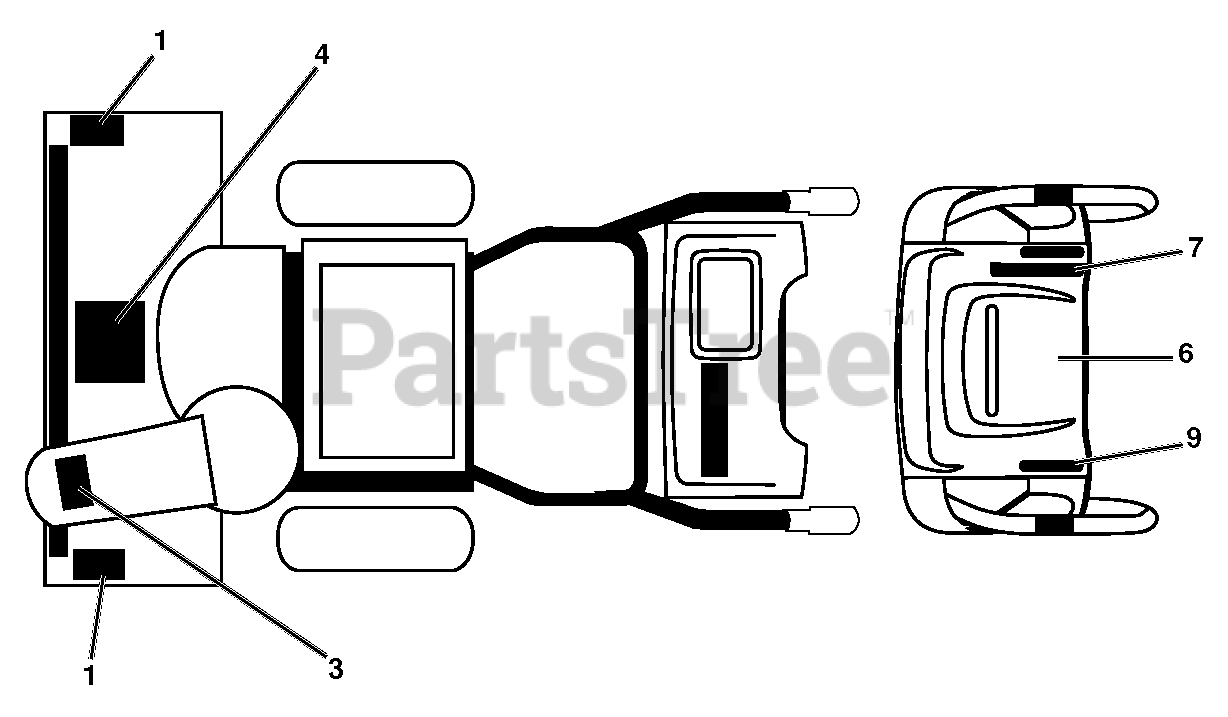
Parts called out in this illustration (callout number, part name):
1	DECAL.SNOWTHR.AUGER
3	DECAL.SNOWTHR.CHUTE.SAFETY
4	DECAL.SNOWTR.READ.OWN.MAN.E/F
6	DECAL.CONSOLE.SNOW.INST.ENG/FR
7	DECAL.CONS.RT.SPD/LEV/PWRST.
9	DECAL.CONS.LT.SPD/LEV/PWRST.
